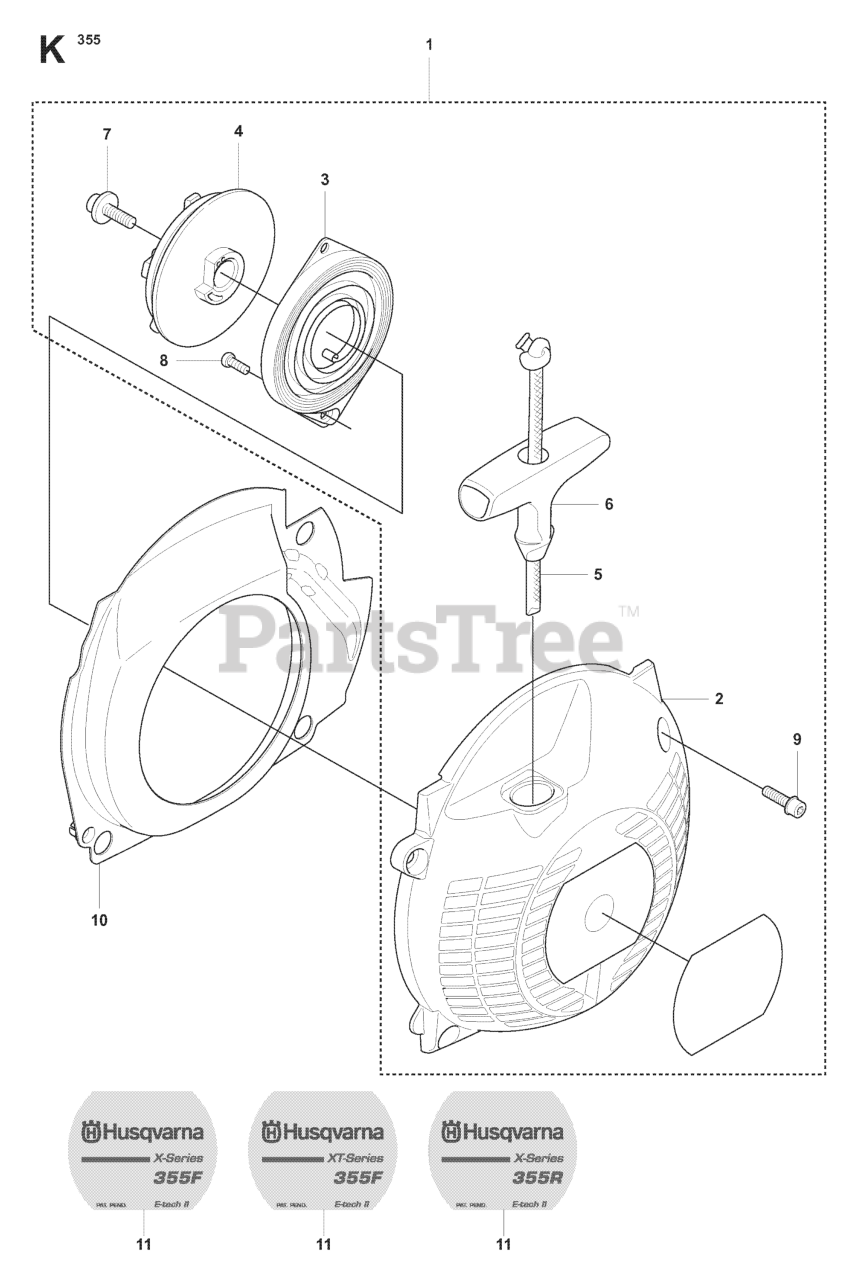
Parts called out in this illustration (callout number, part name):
1	STARTER
2	STARTER HOUSING
3	RECOIL SPRING
4	STARTER PULLEY
5	STARTER ROPE
10	AIR CONDUCTOR
11	LABEL
